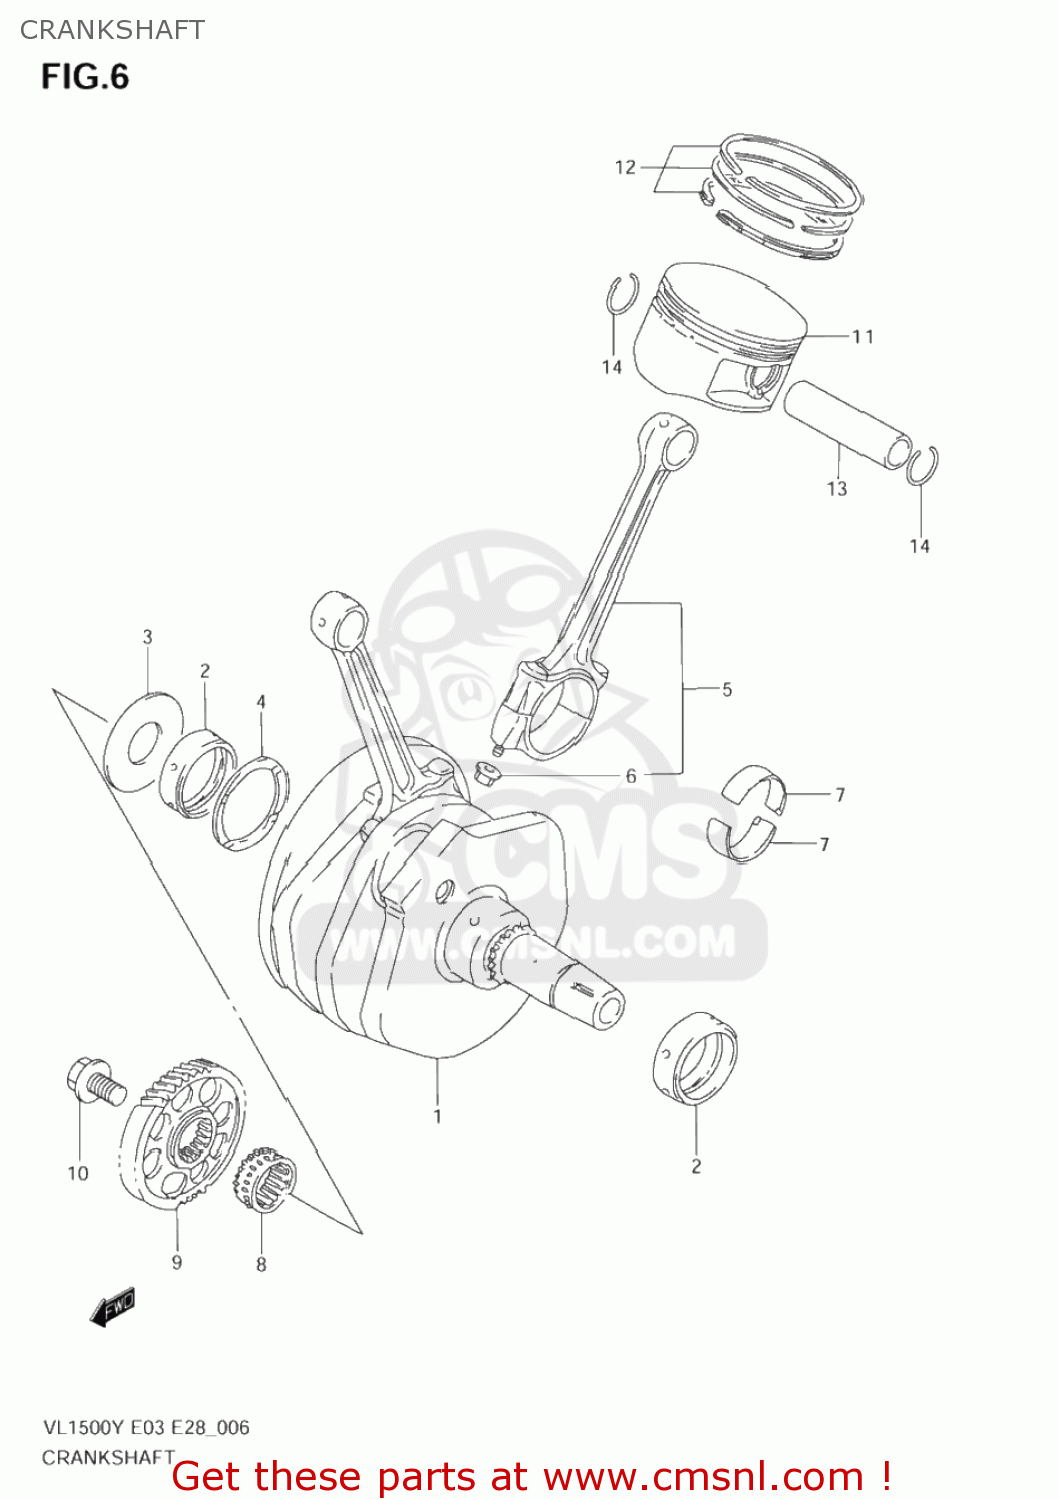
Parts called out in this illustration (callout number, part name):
1	CRANKSHAFT SET
2	METAL,CRANKSHAFT
3	WASHER,CRANK THRUST
4	PLATE,CRANK THRUST
5	CONNECTING ROD ASSY
6	NUT
7	METAL,CRANK PIN
8	SPROCKET,CAM CHAIN DRIVE,R
9	GEAR,PRIMARY DRIVE
10	BOLT(14X28)
11	PISTON
12	RING SET,PISTON
13	PIN,PISTON
14	CIRCLIP
